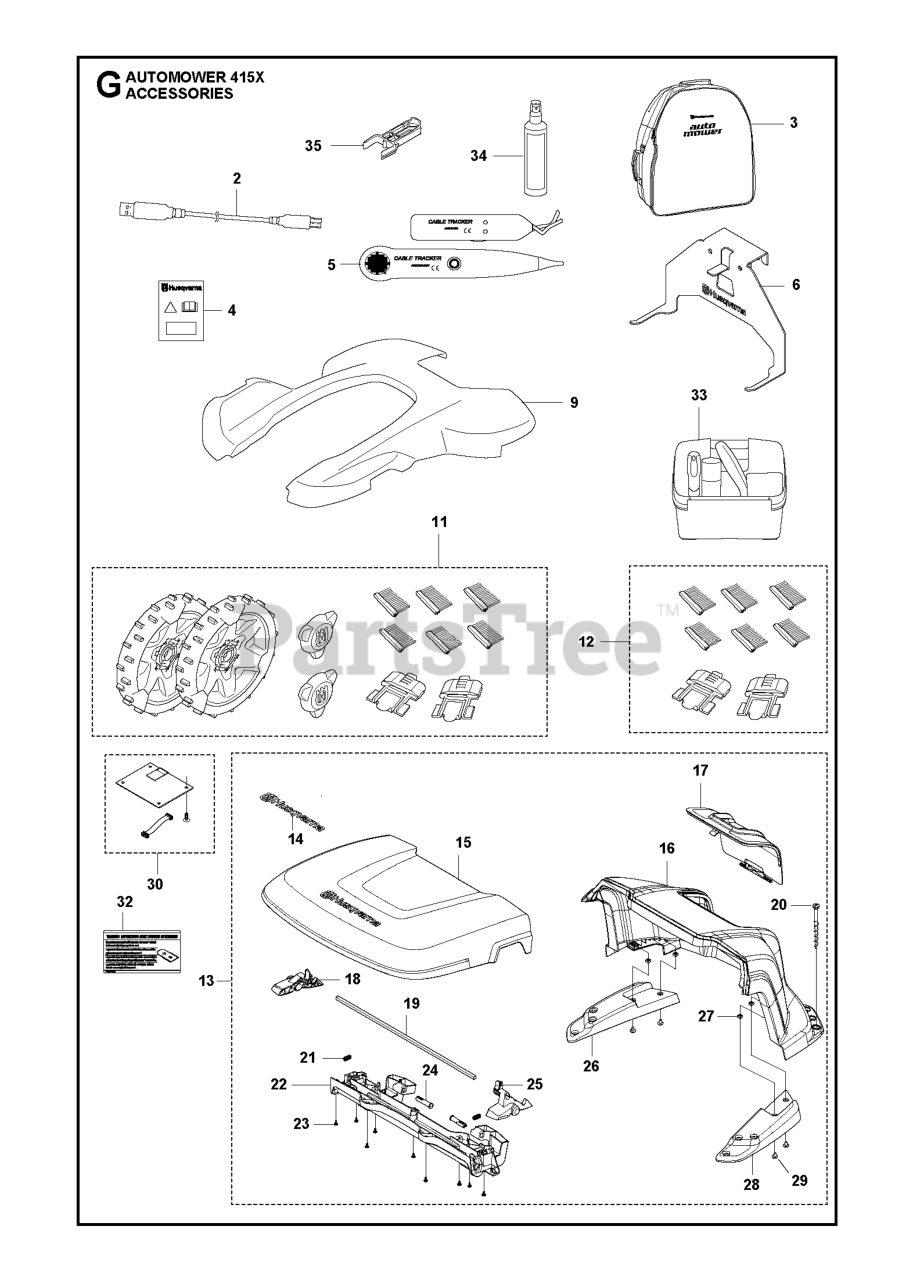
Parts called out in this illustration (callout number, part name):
2	CABLE WHITE ALT GREY
3	BAG
4	LABEL WARRANTY SEAL DEALER
5	TEST EQUIPMENT
12	BRUSH WITH CARTON
13	HOUSE KIT FOR 315
14	DECAL.HUSQVARNA.210MM
15	COVER LID 315
16	COVER BASE P15
17	HATCH
18	HANDLE RELEASE LEFT
19	ROD
20	Screws
21	SPRING SPRING CAP
22	BEAM
23	SCREW 14MM
24	HINGE PIN
25	HANDLE RELEASE RIGHT
26	SUPPORT BASE LEFT
27	NUT
28	SUPPORT BASE RIGHT
29	SCREW IHPANM M6X25 4.6 ZP-BC
30	GPS MODULE 2G + 3G
32	ORIGINAL PARTS STICKER
32	DECAL WARNING ORIGINAL BLADE E
33	CLEANING AND MAITENANCE KIT AM
34	AUTOMOWER ACCY
